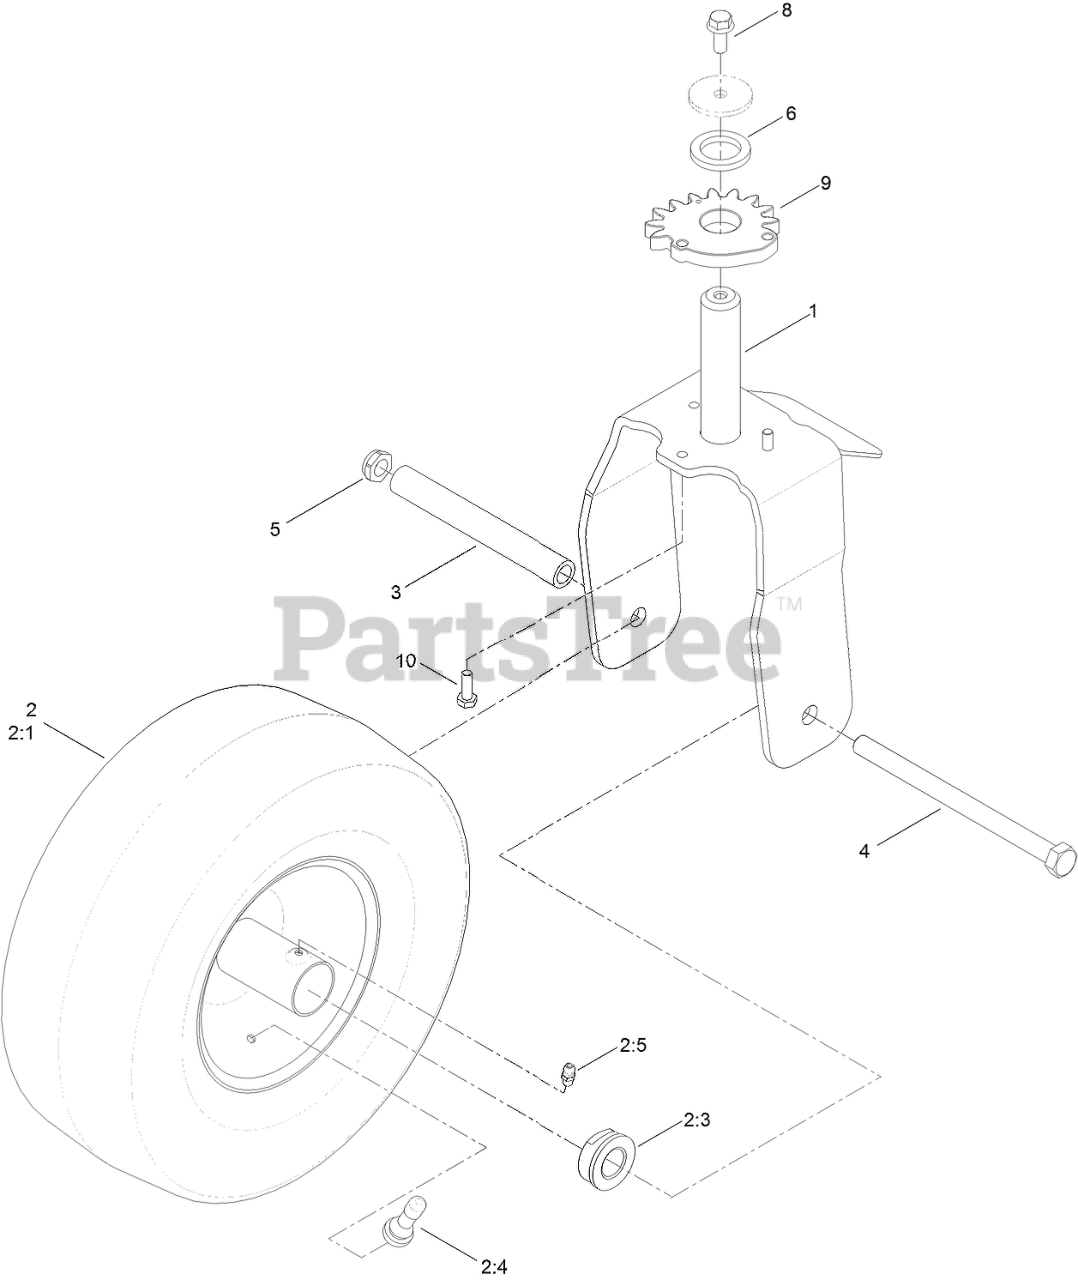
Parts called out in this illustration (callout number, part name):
1	CASTER FORK ASM
2	13 INCH WHEEL AND TIRE ASM
2:1	TIRE-13 Inch
2:3	BUSHING-FLANGE
2:4	STEM-VALVE
2:5	FITTING-GREASE
3	SPANNER
4	SCREW-HH
5	NUT-LOCK, NI
6	WASHER-THRUST
8	SCREW-HHF
9	GEAR-WHEEL, 15 TEETH
10	SCREW-HH
